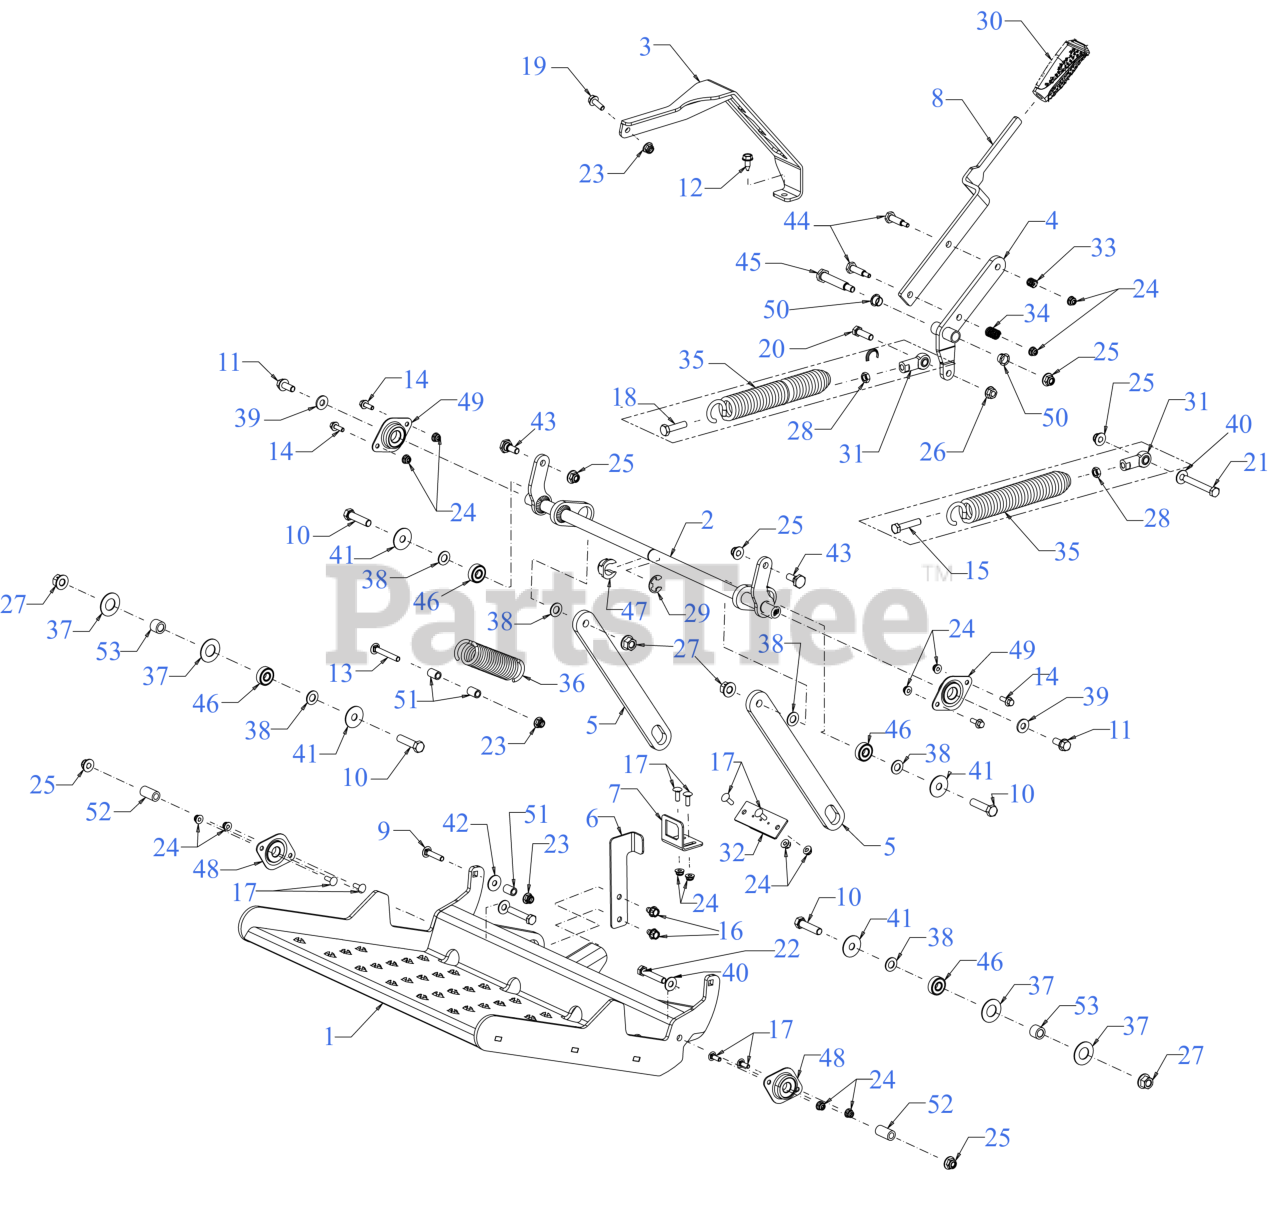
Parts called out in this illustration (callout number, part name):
1	PLATFORM ASSEMBLY
2	ROLLER LINK
3	ADJUSTMENT INDEX
4	ADJUSTMENT ARM
5	SUSPENSION LINK
6	SWITCH BRACKET
7	SWITCH BRACKET MOUNT
8	ADJUSTMENT SPRING LEVER
9	CARRIAGE BOLT 5/16-18 x 1.50
10	SCREW 7/16-20 x 1.75 GR 5
11	SCREW 3/8-16 x .875 GR5
12	SCREW 5/16-18 x .750
13	BOLT 5/16-18 x 2.50 GR1
14	SCREW 1/4-20 x .75 GR5
15	SCREW 3/8-24 x 1.75 GR5
16	SCREW 5/16-18 x .500
17	SCREW 1/4-20 x .75 GR5
18	SCREW 3/8-24 x 1.50 GR8
19	SCREW 5/16-18 x .875 GR5
20	SCREW 3/8-16 x 1.25 GR5
21	SCREW 3/8-16 x 2.75 GR5
22	SCREW 3/8-16 x 2.0 GR 8
23	FLANGE LOCK NUT 5/16-18
24	FLANGE LOCK NUT
26	HEX LOCK NUT
27	FLANGE LOCK NUT
28	HEX JAM NUT 3/8X24
31	ROD END 3/8 ID
32	SUSPENSION BUMPER
33	COMPRESSION SPRING
34	COMPRESSION SPRING
35	ADJUSTMENT SPRING
36	EXTENSION SPRING 1.478 x 5.729
37	FLAT WASHER .760ID X1.49OD x .06
38	FLAT WASHER
39	FLAT WASHER .385X.870X.090
40	FLAT WASHER
41	FLAT WASHER
42	FLAT WASHER 344X1.00
43	SHOULDER SCREW
44	SHOULDER SCREW
45	SHOULDER SCREW .50 x 2.23 3/8-16
46	BALL BEARING
47	HEX FLANGE SPLIT BEARING
48	BALL BEARING
49	BALL BEARING
50	NYLINER BEARING
51	SLEEVE .33X.50X.75 LG
52	SPACER .380x.624x1.040
53	SPACER .465x.760x.550
